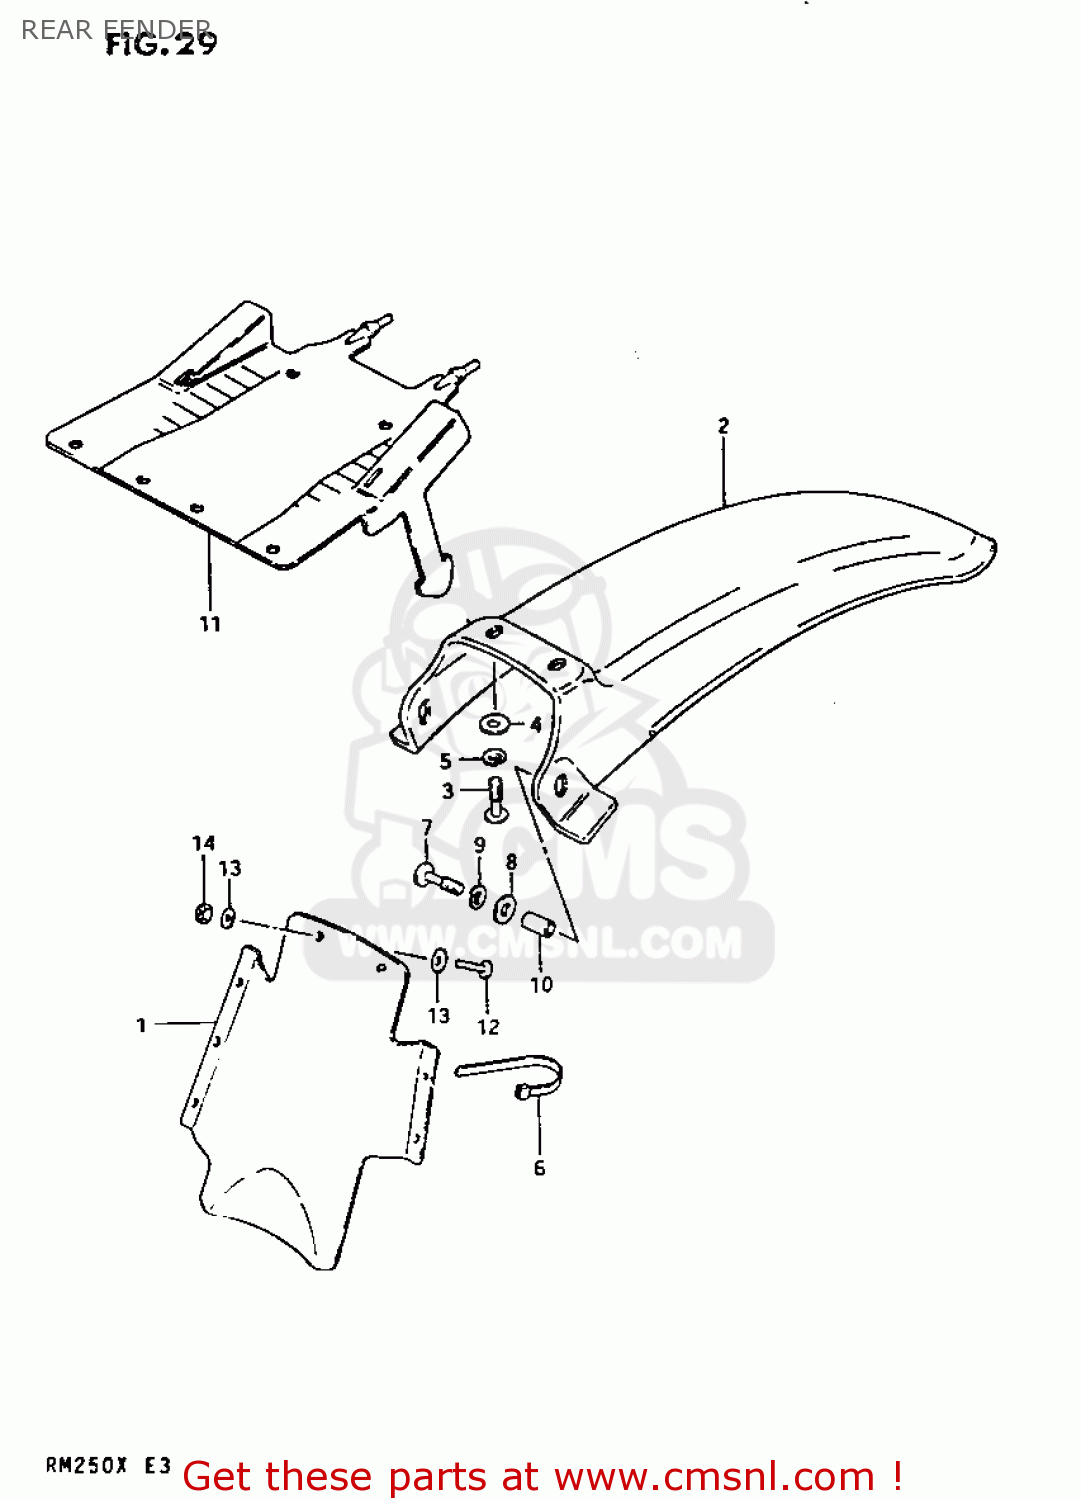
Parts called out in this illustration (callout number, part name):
1	FENDER,REAR
2	FENDER,RR
3	SCREW
4	WASHER (6.5X20X1.2)
5	WASHER,LOCK
6	CLAMP
7	SCREW
8	WASHER (6.5X20X1.2)
9	WASHER,LOCK
10	SPACER
11	GUIDE,RR FENDER MUD
12	SCREW
13	WASHER
14	NUT
